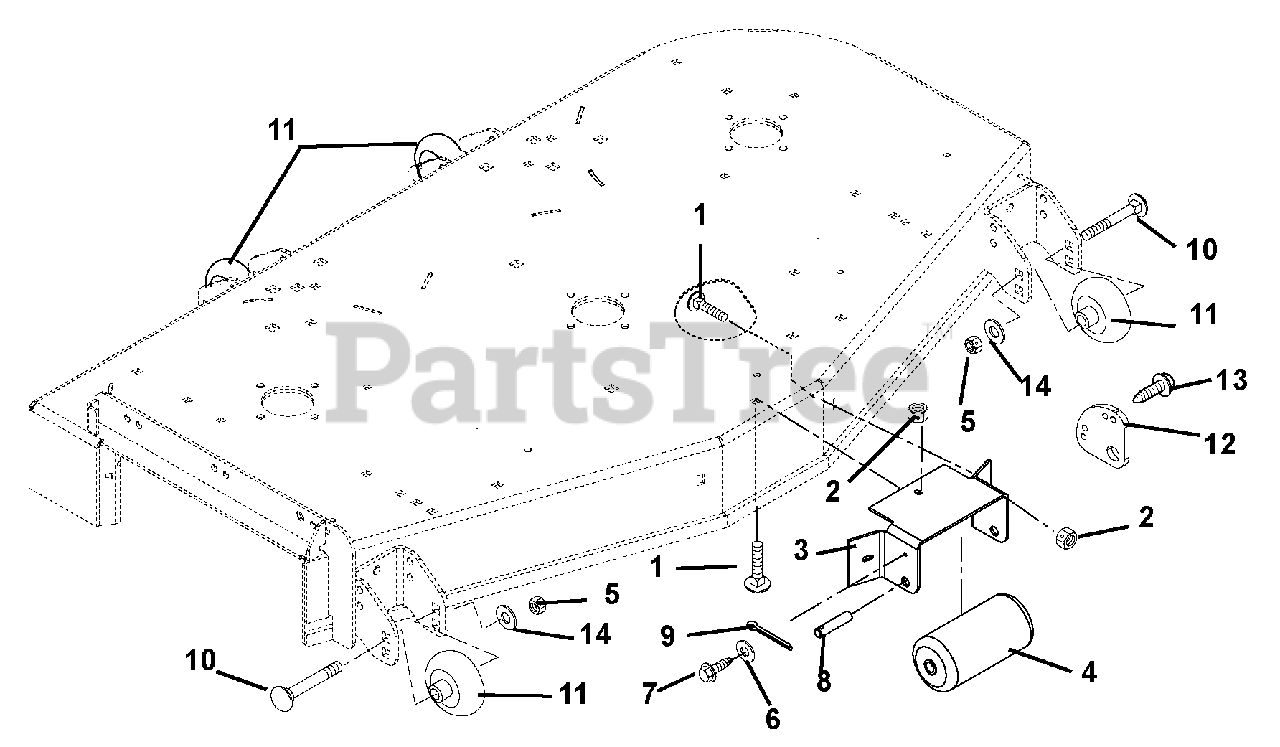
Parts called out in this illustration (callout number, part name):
1	Bolt, Round Head Square Neck .38-16 x 1.00 Grade 5
1	Bolt, Round Head Square Neck .38-16 x 1.25 Grade 2
2	Nut, Locking Top Flange, .38-16
3	Bracket, Anti-Scalp Roller
5	Nut, Locking Nylon .50-13
6	Washer, Flat Steel .281 x .62 x .065
7	Screw, Tapping .25-20 x .75 Hex Washer Head
9	Pin, Cotter .25 x 2.0
10	Bolt, Round Head Square Neck .50-13 x 5.00 Grade 2
11	Wheel, 3 x 5
12	Anti-Scalp Washer
13	Screw, Tapping .25-20 x .62 Hex Washer Head
14	Washer, Flat Steel .531 x 1.06 x .095
